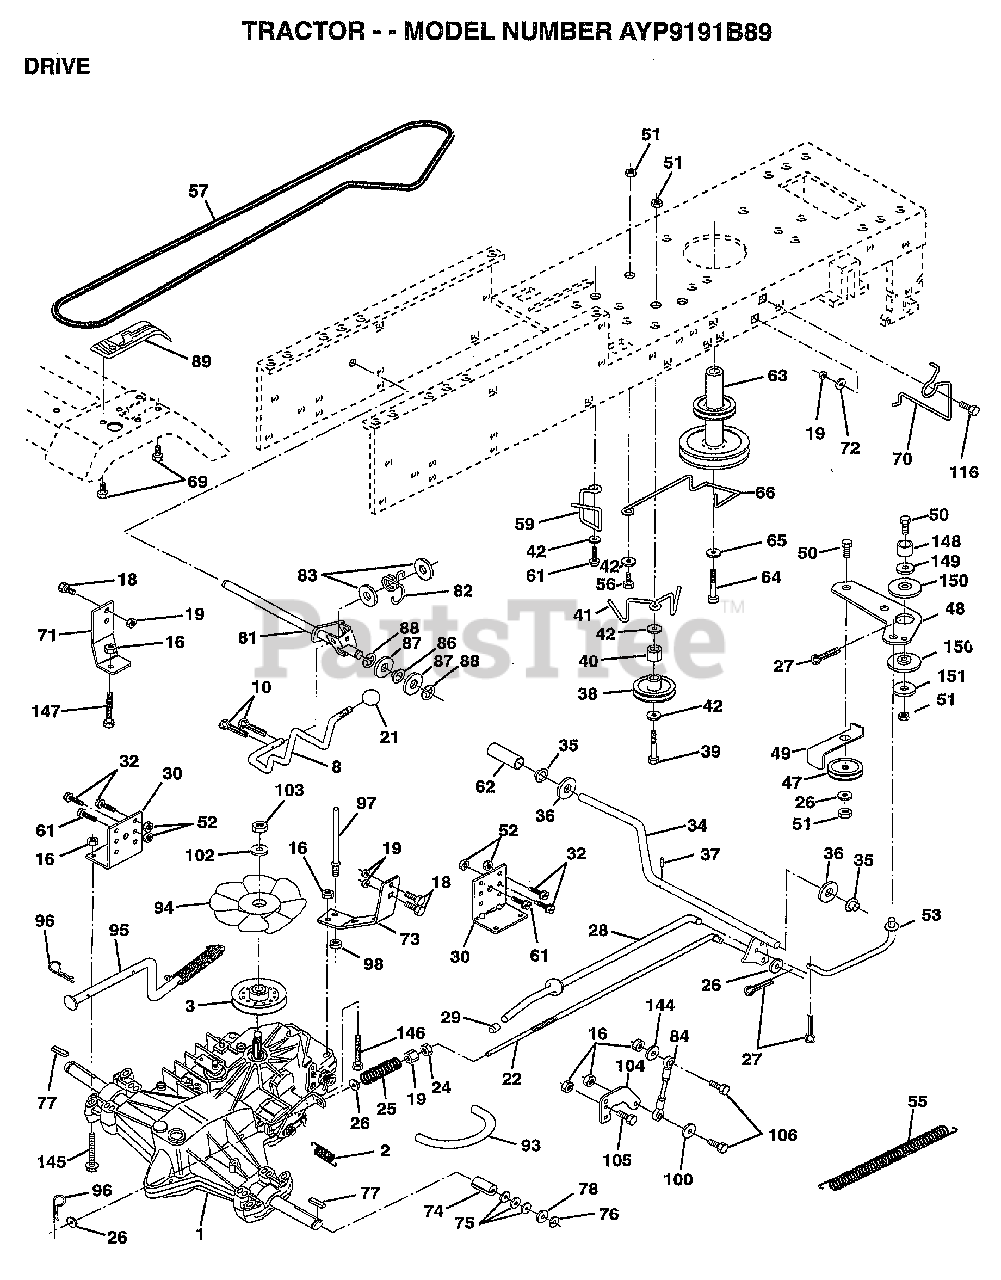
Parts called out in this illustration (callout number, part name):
1	TRANSAXLE.3100650
2	SPRING RET BRAKE
3	PULLEY.TRANSAXLE
8	ROD SHIFT FEND LT
10	PIN COTTER 1/8
15	BOLT.HX.FLG.5/16
16	NUT
18	BOLT
19	NUT
21	KNOB T (1/2-HOLE)
22	ROD.BRAKE.HYDRO.
24	NUT
25	SPRING ROD LT
26	WASHER
27	COTTER PIN
28	ROD.BRAKE.PARK.LT
29	PLUNGER CAP T
30	TRANSAXLE MTG BKT
32	BOLT
34	SHAFT ASM-PEDAL F
35	NYLON BEARING
36	WASHER LT
38	PULLEY.IDLER.FLAT
39	BOLT
40	SPACER T
42	WASHER
43	WASHER T
48	BELLCRANK.CLUTCH
49	RETAIN BELT
53	"LINK, CLUTCH T"
55	"SPRING, RETURN LT"
57	"BELT.GD DRV 82"""
59	KEEPER BELT CNTSP
61	SCREW
62	PEDAL COVER T
63	PULLEY.ENGINE
64	BOLT
65	LOCKWASHER
66	KEEPER-BELT
69	SCREW HEXWSH H-L
70	KEEPER BELT ENG
71	STRAP TORQ LH HYD
72	WASHER
73	"STRAP-TORQUE,RH"
74	SPACER SPLIT
75	WASHER
76	E-RING LT
77	SQUARE KEY
78	WASHER
81	SHAFT.CROS.20.HYD
82	"SPRING,TORSION"
83	WASHER
84	ROD.TIE
86	BUSHING
87	WASHER D
88	KLIP RING
92	HEX BOLT
93	"LINE FUEL HYD 4"""
94	"FAN 7"" HYDRO"
96	RETAINER M
97	BOLT KEEPER RH
98	NUT
100	WASHER M
102	WASHER BELLEVILLE
104	ARM CONTROL HYDRO
105	SCREW CAP 5/16-18
106	BOLT
116	BOLT RDHD 3/8-16
144	WASHER
146	BOLT.HEX.FLGHD.
147	BOLT.HEX.FLGHD
149	SPACER RETAINER
150	BUSHING.NYLON
151	WASHER
